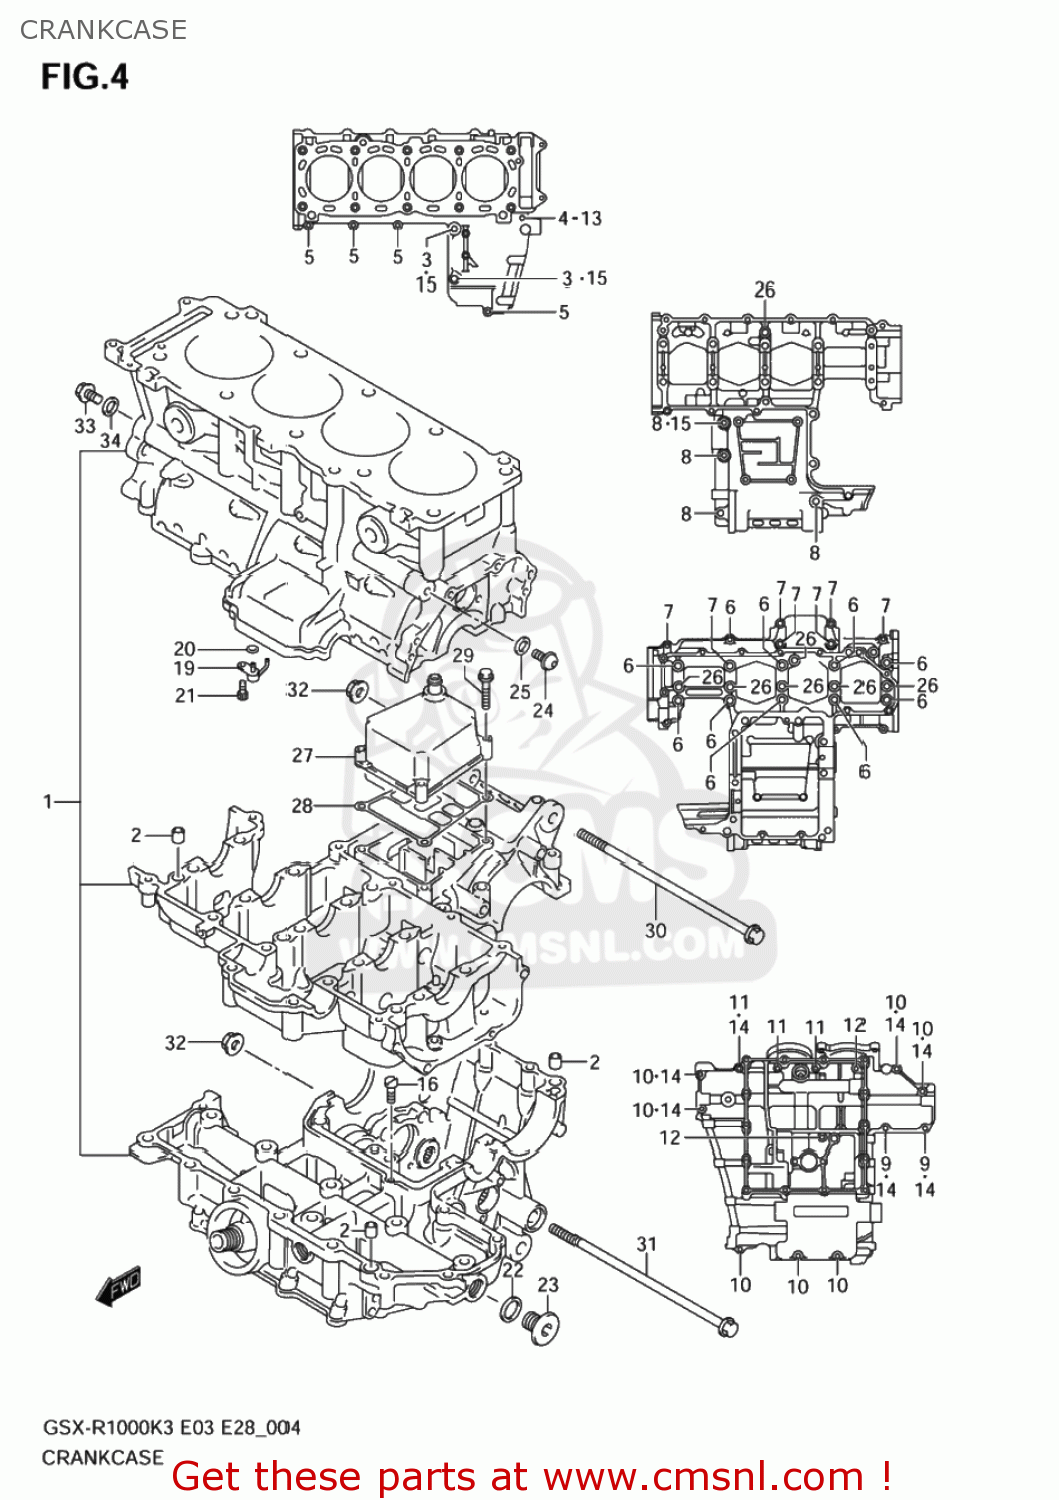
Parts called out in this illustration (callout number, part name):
1	CRANKCASE SET
2	PIN,CRANKCASE
3	BOLT(8X120)
4	GASKET(5.8X13X1.2) (NAS)
5	BOLT
6	BOLT(9X95)
7	BOLT
8	BOLT
9	BOLT,G/S SWITC
10	BOLT
11	BOLT
12	BOLT
13	BOLT
14	GASKET(5.8X13X1.2) (NAS)
15	GASKET(8.2X14X1) (NAS)
16	JET(140)
17	BEARING,CRANK THRUST(GREEN)
18	BEARING,CRANK THRUST(RED)
19	JET,PISTON COOLING
20	O RING(D:1.2,ID:4)
21	BOLT(6X12)
22	GASKET(16X22X2) (NAS)
23	PLUG
24	PLUG(10X10)
25	GASKET(10X14X3.6) (NAS)
26	O RING(D:1.9,ID:7.8)
27	COVER,BREATHER
28	GASKET,BREATHER COVER (NAS)
29	BOLT,G/S SWITC
30	BOLT 10X215
31	BOLT 10X215
32	NUT
33	BOLT
34	GASKET(8.2X14X1) (NAS)
